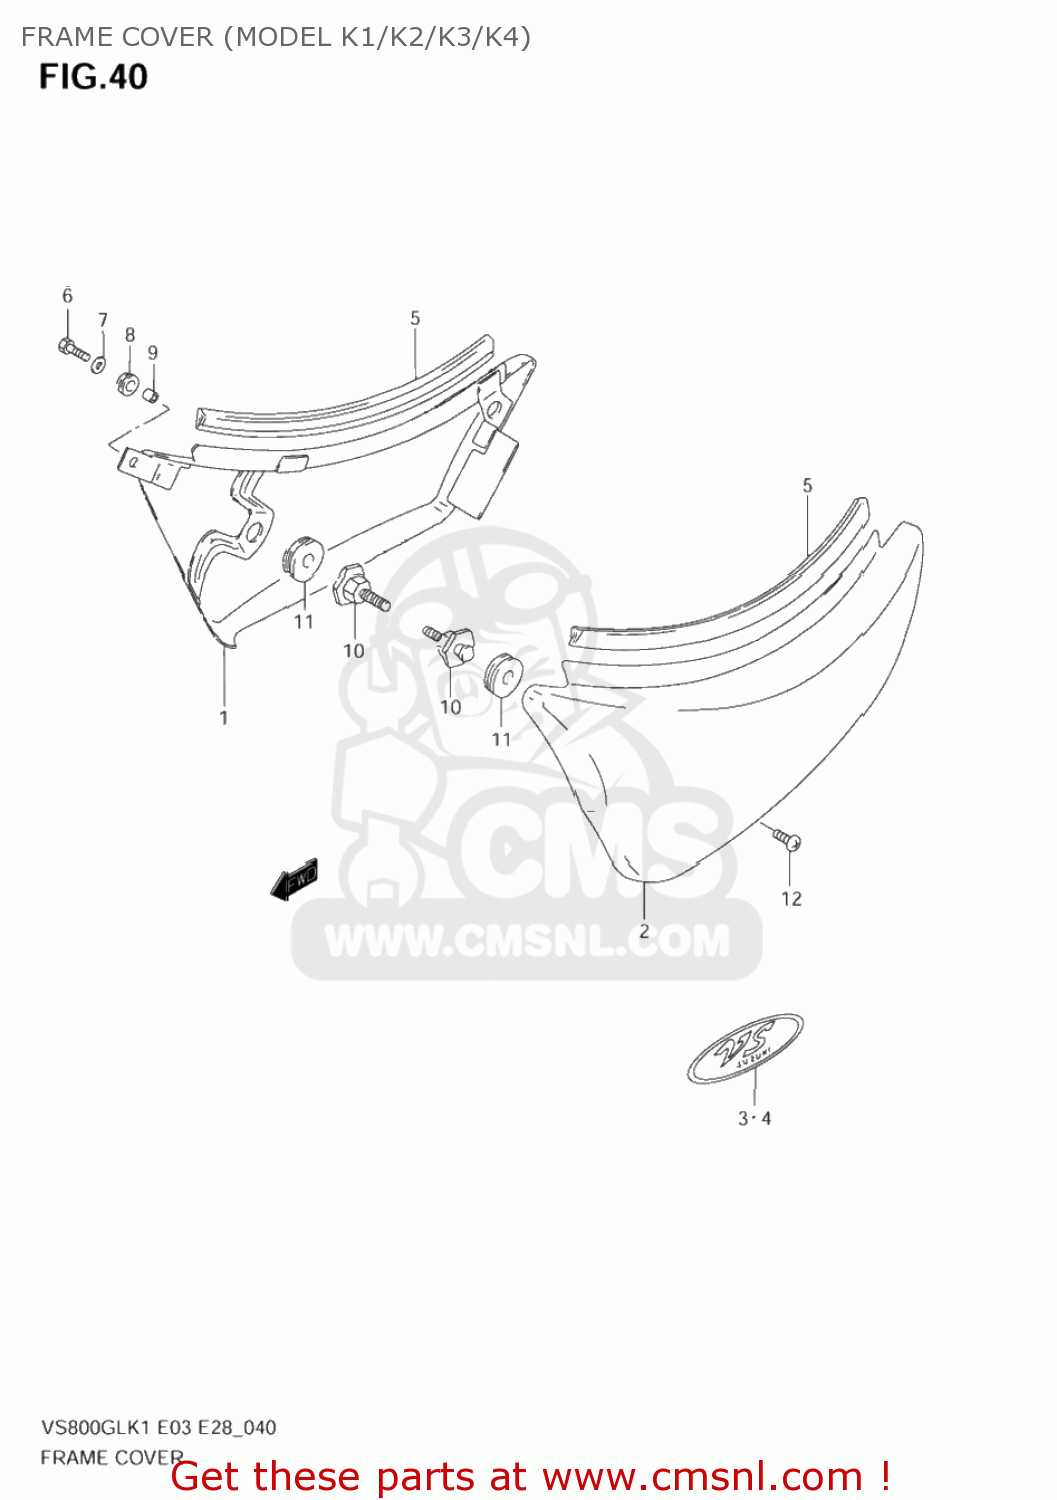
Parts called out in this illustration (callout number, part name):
1	COVER,FRAME,R(RED)
2	COVER,FRAME,L(RED)
3	EMBLEM,FRAME COVER
4	EMBLEM,FRAME COVER
5	MOLDING
6	BOLT
7	WASHER(6.5X18X1.6)
8	CUSHION
9	SPACER(6.1X8X5.2)
10	BOSS,FRAME COVER
11	CUSHION
12	SCREW 6X10
